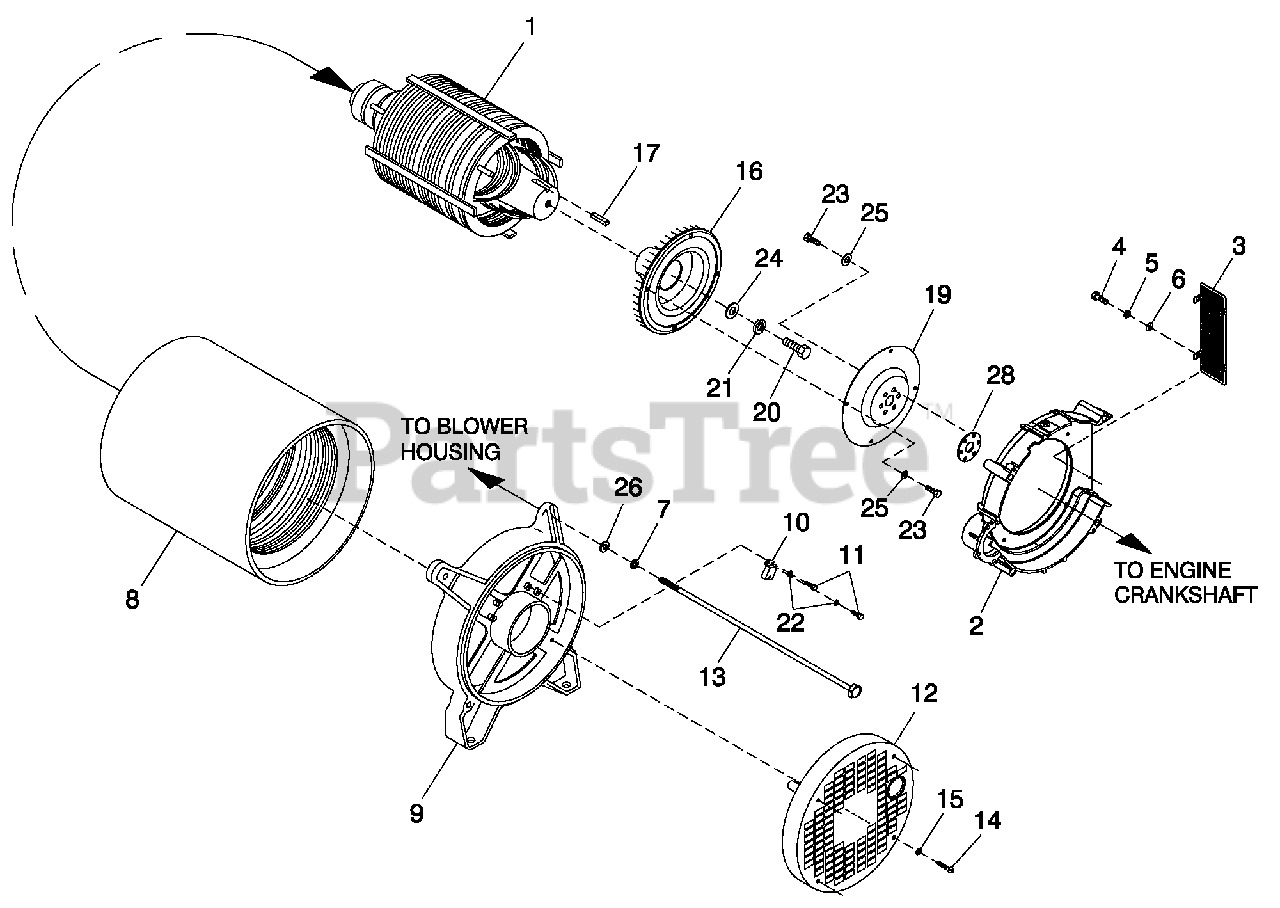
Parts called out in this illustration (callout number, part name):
1	RTR-102-20.0AD1 CPL (2006) (FOR UNITS BUILT AFTER FEBRUARY 2007)
2	HOUSING BLOWER MACHINED 1.6L
3	GUARD BLOWER HOUSING 1.6L
4	SCREW PPHM M5-0.8 X 8 ZINC
5	WASHER LOCK M5
6	WASHER FLAT M5
7	WASHER LOCK M8-5/16
8	STR 102 20AD1 CPL (FOR UNITS BUILT BEFORE FEBRUARY 2007)
9	BEARING CARRIER REAR
10	ASSY HOLDER BRUSH
11	SCREW HHC M4-0.7 X 16 G8.8
12	COVER REAR BEARING
13	BOLT STATOR X 16" LG
14	SCREW RHM #10-24 X 2
15	WASHER LOCK #10
16	FLYWHEEL & RING GEAR ASSY 1.6L
17	KEY SQ 3/8 X 1 STEEL
19	PLATE FLEX 1.6L R12.7
20	SCREW HHC M12-1.75 X 35 G8.8
21	WASHER LOCK M12
22	WASHER SHAKEPROOF INT #8
23	SCREW HHC M10-1.0 X 20 G10.9
24	SPACER ROTOR SHAFT
25	WASHER .41 ID .94 OD .12 THK
26	WASHER FLAT .34 ID X .75 OD
28	PLATE SPACER 14GA 1.6L
